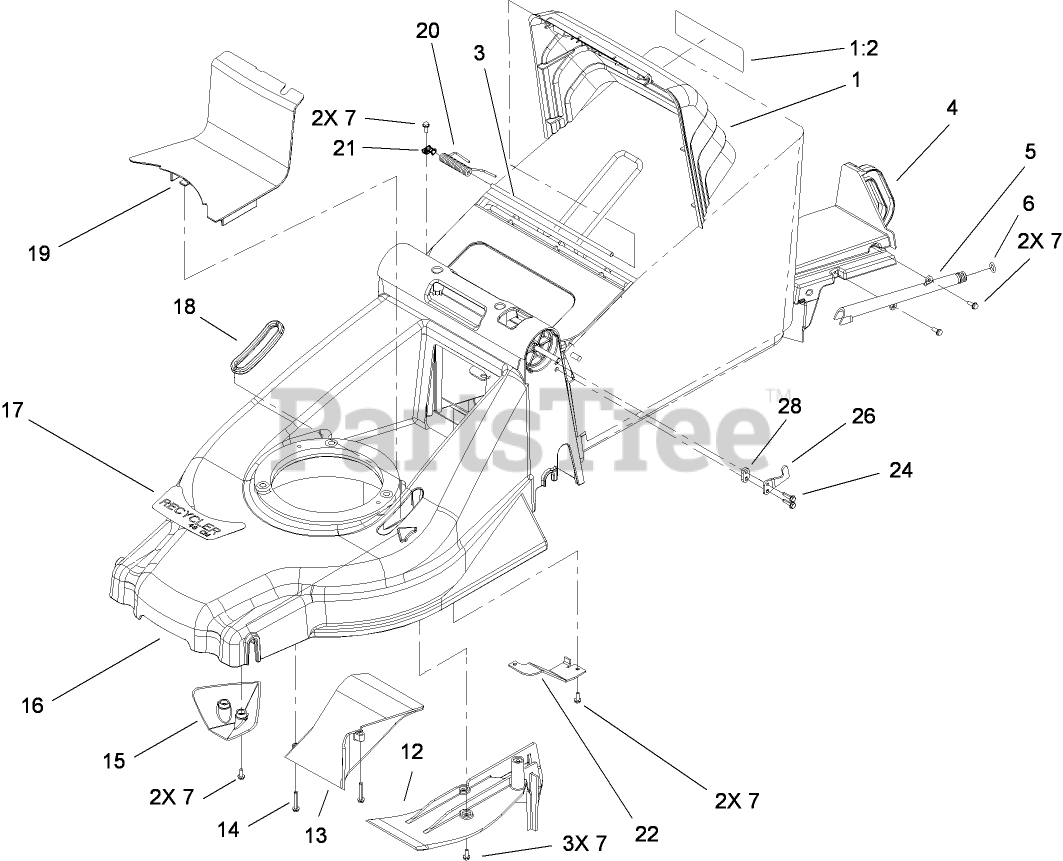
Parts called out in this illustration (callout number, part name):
1	DOOR ASM
1:2	DECAL-WARNING
3	ROD-PIVOT
4	PLUG-KICKER, RECYCLER
5	FITTING-WASHOUT
6	O-RING
7	SCREW-TAPTITE
12	COVER-KICKER, REAR
13	RAMP-DISCHARGE
14	SCREW-HWH
15	KICKER-FRONT
17	DECAL-RECYCLER, DECK
18	BOOT-HOC
19	COVER-BELT
20	SPRING-TORSION
21	CLAMP
22	BRACKET-DECK
24	SCREW-HWH
26	HOOK-LEFT
28	SPACER
